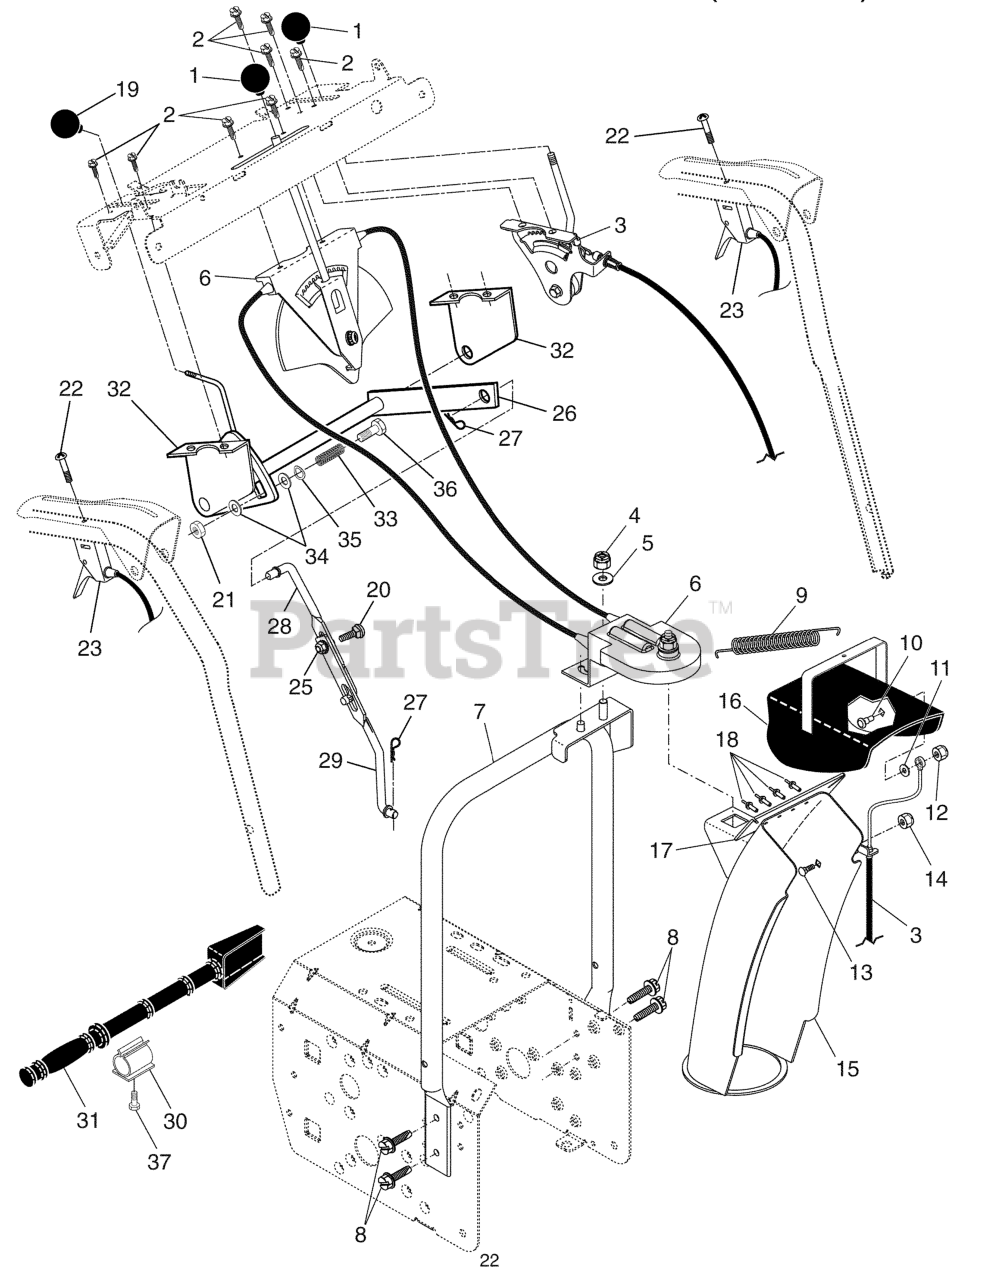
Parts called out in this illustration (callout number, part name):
1	KNOB LEVER, BLACK
2	SCREW #10-24 X 5/8
3	CONTROL.CABLE.DEFLECTOR
4	NUT
5	WASHER
6	CONTROL ASSEMBLY,CHUTE ROTATER
7	SUPPORT.PIVOT.WELD
8	SELF-TAPPING SCREW 5/16-18X3/4
9	SPRING.DEFLECTOR.REM.CHUTE
10	BOLT, SHOULDER
11	WASHER, NYLON FRICTION
12	NUT.HEX.FLANGE.1/4
13	BOLT
14	NUT.LOCK.5/16-18
15	CHUTE ASSEMBLY
16	DEFLECTOR.WELDMENT.PNT.ORANGE
17	SEAL, DEFLECTOR
18	RIVET BLIND
19	RED KNOB SHIFTER
20	BOLT
21	NUT.71038.31-18.HEX.NYLOCK
23	CABLE.ASM.STEER.GT.BLUE
25	NUT.FLANGE.5/16
26	SHIFT.WELDMENT.GT.SNOW
27	SPRING RETAINER
28	ROD, UPPER SPEED CONTROL
29	ROD.SPEED.LOWER.GT
30	CLIP.CLEANOUT.TOOL
31	CLEAN OUT TOOL
32	BRACKET, SHIFT
33	SRPING.FRICTION.HYDRO
34	WASHER.20X8.5
35	WASHER, NYLON FRICTION
37	SCREW.HWH.13-16-5.8.BZP
